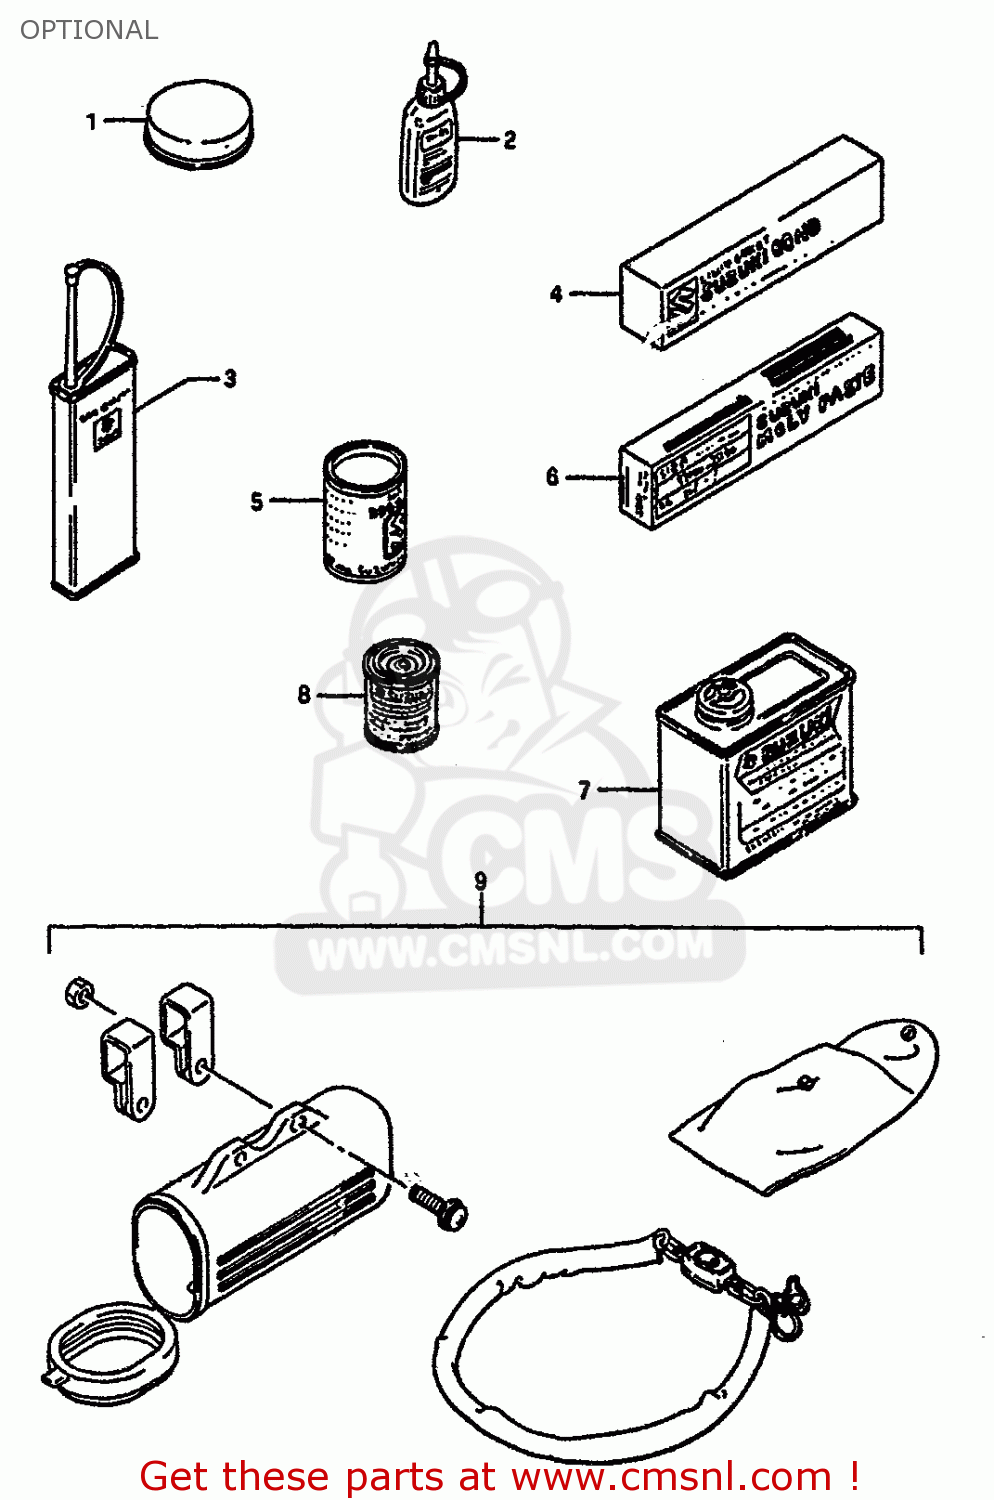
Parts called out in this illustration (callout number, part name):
1	GREASE,PBC FOR BRK PAD 20G
2	THREAD LOCK NO.1342
3	THREAD LOCK NO.1401 CLEAR 200G
4	LIQUID GSKT NO.1207B 100G BLK
5	GREASE(C)EP2 LITHIUM 150G
6	SUZUKI MOLY PASTE
7	PAINT (BLACK)
8	PAINT,BLACK
9	LOCK SET,CHAIN
